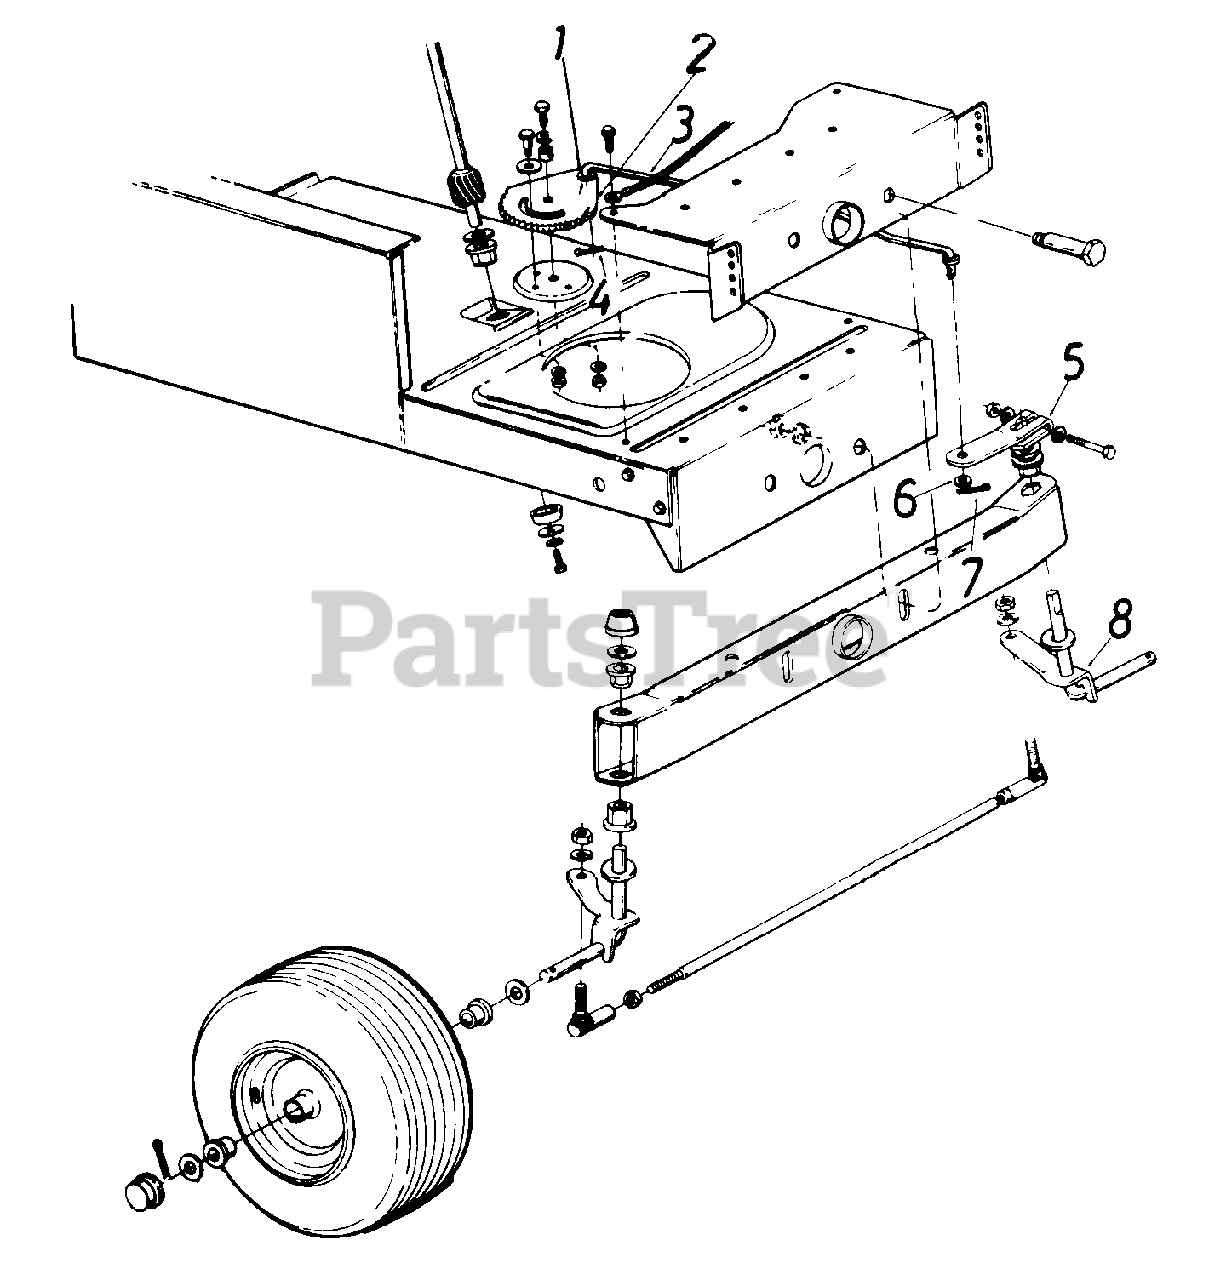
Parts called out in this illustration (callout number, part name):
1	Fl.-Wash..56" I.D. x 1" O.D.
2	Steering Gear Segment
3	Steering Drag Link
4	Cotter Pin 1/8" Dia. x 1" Lg.
5	Steering Arm Front Axle
6	Fl.-Wash..56" I.D. x 1" O.D.
7	Cotter Pin 1/8" Dia. x 1" Lg.
8	Front Axle Ass'y. - L.H. - Short
